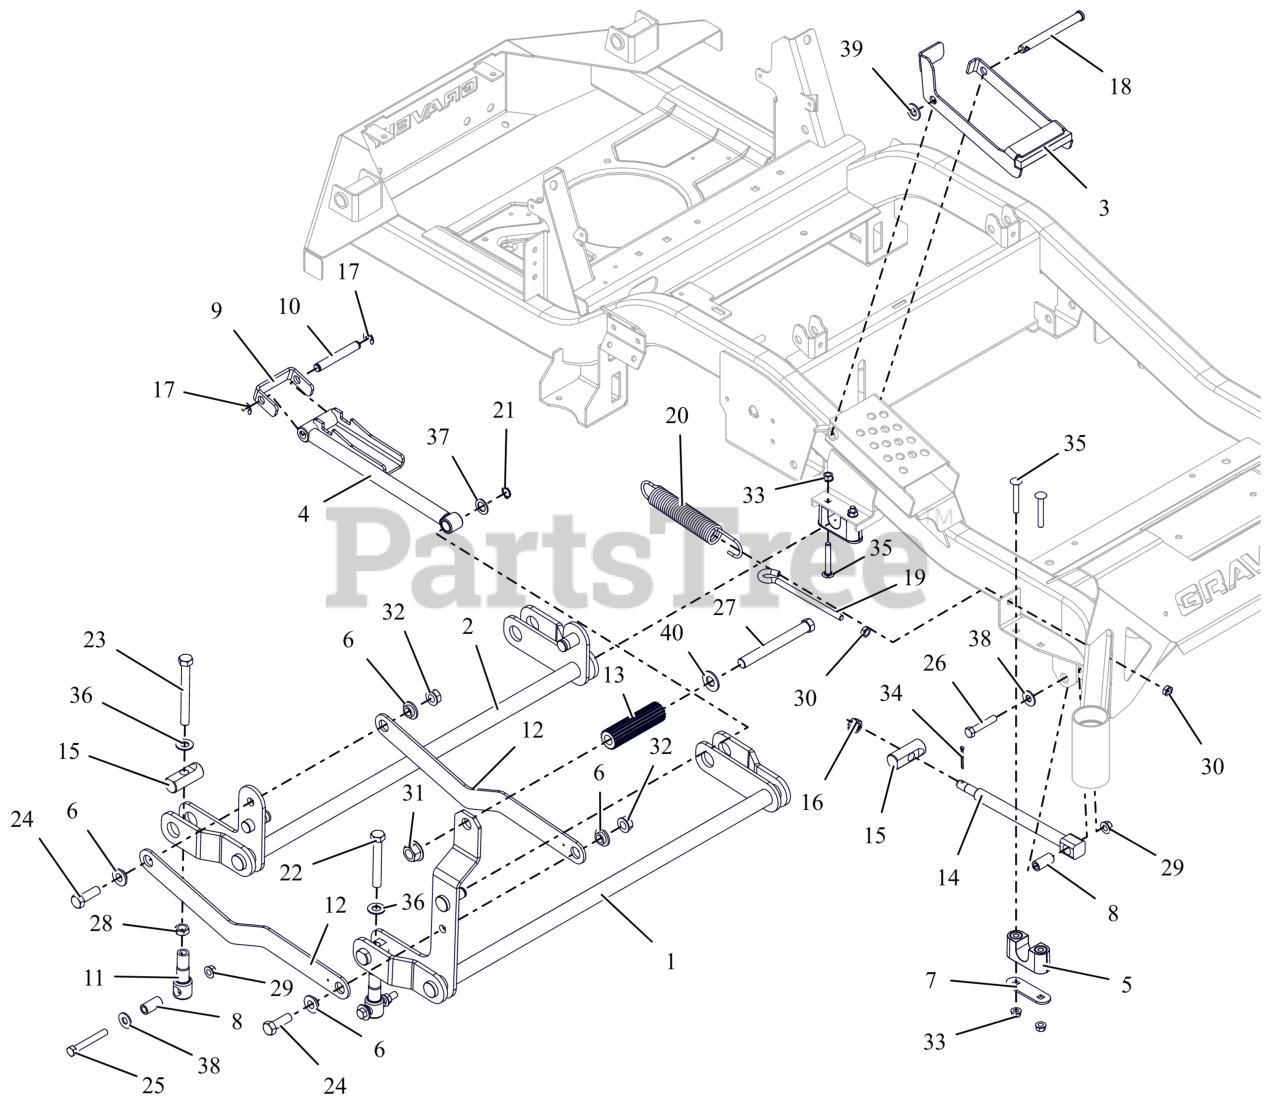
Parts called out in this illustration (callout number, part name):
1	WLDMT, FRONT DECK LIFT PIVOT
2	WLDMT, REAR DECK LIFT PIVOT
3	BRKT, HOC TRANSFER LOCK
4	WLDMT, HOC ARM
5	ASM-BUSHING, DECK LIFT
6	BSHG-FLG .515X.750X.310X1.120
7	PLATE, BEARING SUPPORT
8	SPACER, DECK LEVELING
9	BRKT, HOC LINE
10	ROD, HOC PIVOT
11	LINK, DECK LIFT FORMED
12	LINK, DECK LIFT
13	ROD, FOOT PEDAL (BLACK)
14	DRAG,LINK-HD
15	PIN, DECK LIFT
16	NUT-SL .50-13
17	RG-RTNG-EXT .500X.042 (E)
18	PIN, SLIC-.500X4.97X4.55 -ZC
19	BOLT,.38-16 X 5.25-.62 DIA EYE
20	SG-TENS .162X1.25X8.25 WLD 25
21	RG-RTNG-EXT .625X.050
22	BLT, HEX 0.5-13X3.5F GR5 ZCC
23	BLT, HEX .50-13X4.50F G8 ZCC
24	BLT,HEX .50-13X1.50 G5 ZCC
25	BLT, HEX .38-16X2.75 G8 ZCC
26	BLT,HEX .38-16X2.00 G5 ZCC
27	BLT, HEX .62-11X5.50 G5 FBP
28	NUT-JAM .500-13 G2 ZCC
29	NUT-LK-TOP-FLG .38-16 ZC120
30	NUT-JAM .375-16 G2 ZCC
31	NUT,FLG-TOP LK .625-11 FBP
32	NUT-LK-TOP-FLG .500-13 GF ZCC
33	NUT,LK-CTR-FLG .31-18 GF ZCC
34	PIN,CTR.12X1.25EXTPRSQCT ZC120
35	BLT, RHSSN.31-18X2.25 G5 ZCC
36	WSHR, FLT .557X1.040X.102 ZCC
37	WSHR, FLT .630X1.005X.062 ZCC
38	WSHR,FLT .438X1.00X.083 ZCC
39	WSHR,FLT .531X1.062X.095 ZCC
40	WSHRFLT 5/8SAE CARBHARD FBP
